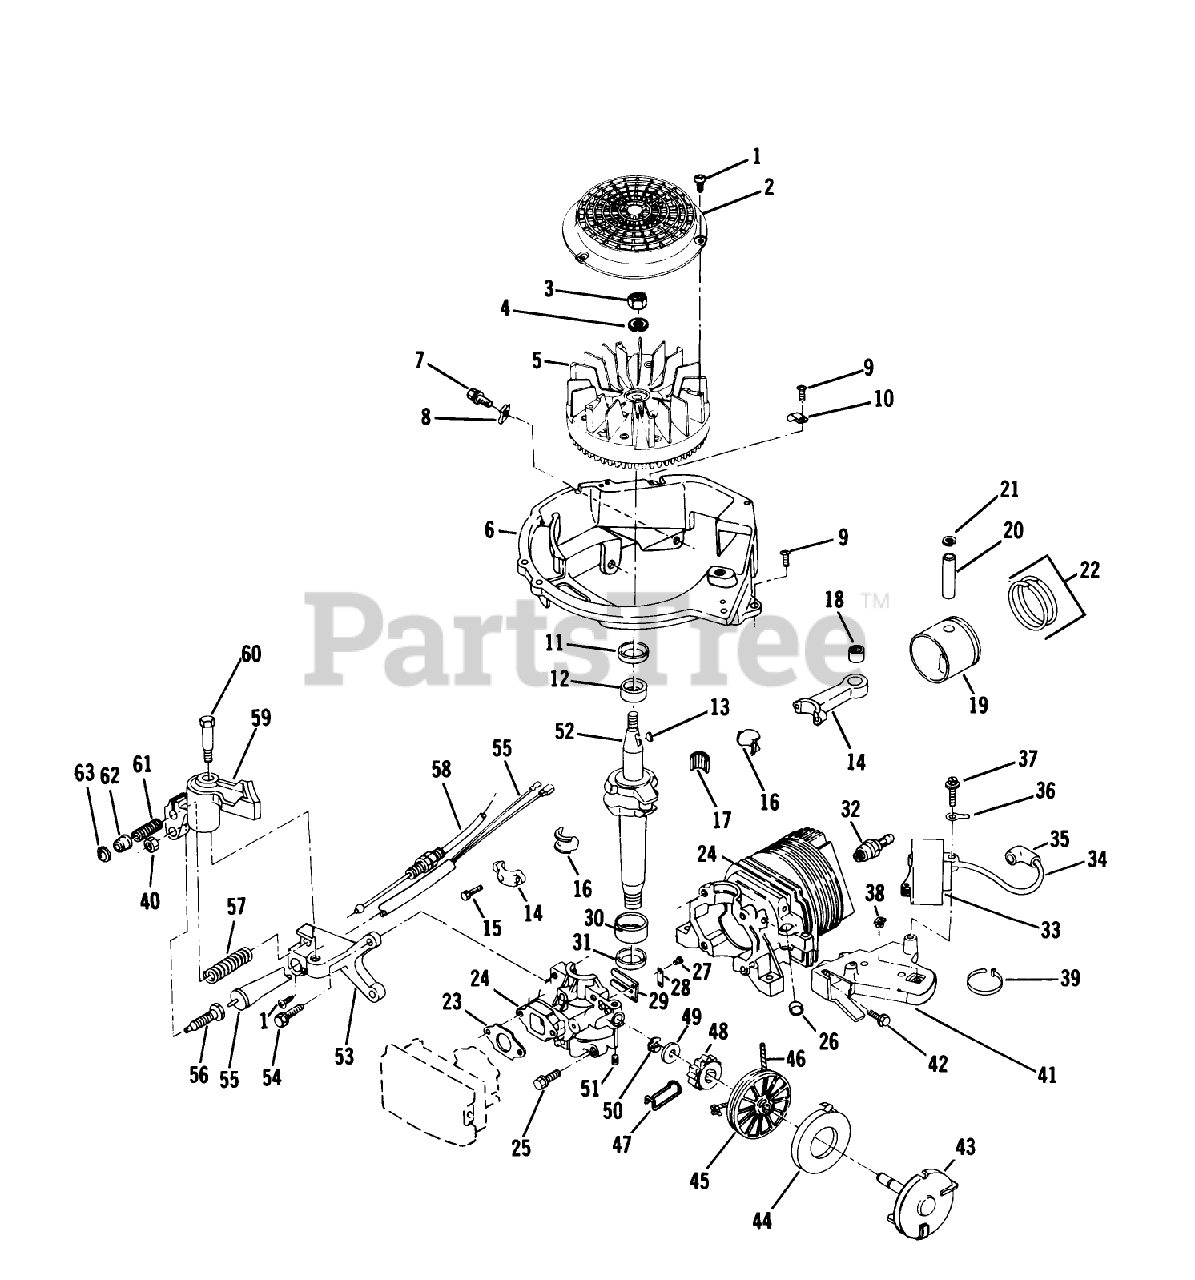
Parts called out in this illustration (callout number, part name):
1	SCREW F
2	SCREEN F'WHEEL S
3	NUT
7	SCREW-SEMS
9	SCREW F
12	BEARING V
13	KEY
15	SCREW-HSH
16	LINER ASM
18	BEARING AY F
21	RING-RETAINING
23	GASKET CARB S
25	SCREW S
26	PLUG-CORE VF
28	PLATE-BACKUP, REED
30	BEARING V
31	SEAL-OIL
34	HT LEAD&COVER XEV
36	TERMINAL S
38	NUT-CLIP
41	BRACKET S
43	SPRING CUP&PIN S
44	SPRING&RET.AY S
45	PULLEY STARTER S
46	ROPE-STARTER
49	WASHER S
53	BRACKET-BRAKE F
56	PLUNGER S
57	SPRING-BRAKE
58	CONTROL CABLE AY
61	SPRING
62	ACTUATOR-LEVER, BRAKE
63	RETAINER S
